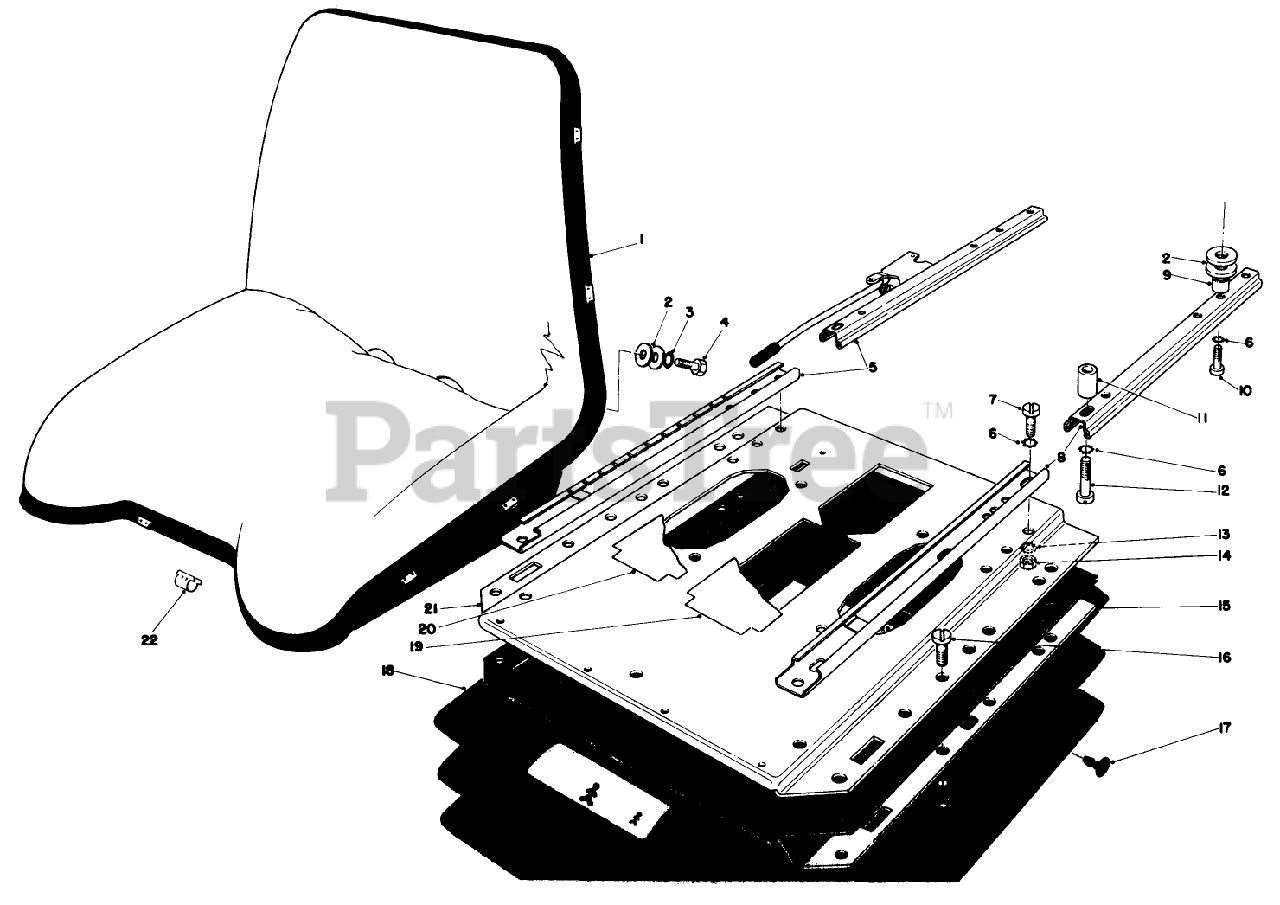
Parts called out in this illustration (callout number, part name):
1	Seat Bucket Complete
2	Washer 13 MM
3	Serrated Washer
4	Capscrew 7/16-20 U.N.F.
5	Fender
6	Serrated Washer
7	KNOB-THROTTLE
8	Adjustment Track
9	Sleeve
10	PLATE-FRONT AXLE R
11	TORQUE STRAP RH R
12	Cylinder Bolt
13	Spring Washer
14	Nut M8
16	Capscrew
17	PULLEY-PTO TRANSM R
18	Rubber Bellows
19	Cover
20	TORQUE STRAP LH R
21	Upper Suspension Plate Complete
22	Clamps Outside
